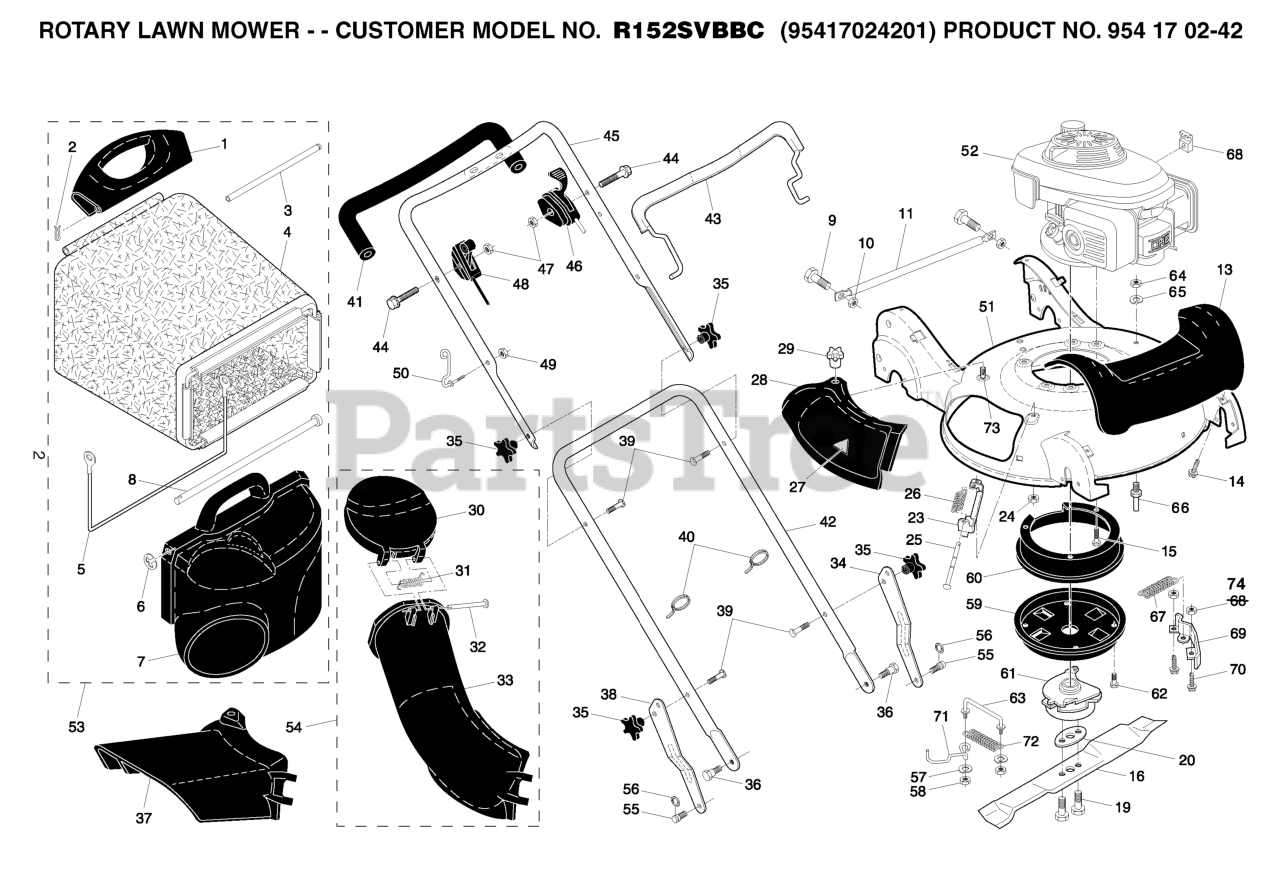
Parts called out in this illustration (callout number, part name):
1	HANDLE.GRASSBAG.REAR.H-GRAY
2	COTTER PIN (3 2)(2 2MC)
3	ROD.REAR.HANDLE.YELLOW
5	FRAME, GRASSBAG
7	DOOR, GRASSBAG
8	ROD, PIVOT
10	LOCKNUT.NYLOC.1/4-20
11	TUBE, REAR SKIRT
13	COVER, FRONT
14	SCREW
15	BOLT 3/8-16X1-1/8
16	BLADE.21".BBC
23	BRACKET.ASM.HINGE
24	LOCK NUT
25	ROD.HINGE.1/4"3.82"
26	SPRING.MULCH.DOOR
27	DECAL.INTERNATIONL.CUTFINGER
28	MULCHER DOOR
29	KNOB.MULCH.DOOR
30	CHUTE.DOOR.21.HV.H-GRAY
32	ROD.HINGE.1/4"3.82"
33	DISCHARGE CHUTE PLASTIC
34	ADJUSTMENT BRACKET, LOWER LH
35	KNOB.HANDLE.STAR.HUSQ.GRAY
36	SHOULDER BOLT
37	GUARD.CLIP.ON.21.HV.GRAY
38	BRACKET.ADJ.LOWER.HDL.RT.GREY
39	BOLT, HANDLE 5/16-18X1.75
40	TIE GUIDE
41	GRIP.HANDLE.FOAM.WIDE.(1 SIDE)
42	HANDLE.LOWER.GREY
43	BAIL
45	HANDLE.ASM.UPPER.W/GRIP
46	CONTROL.BBC.HV.GRY/ORG
47	NUT
48	THROTTLE CONTROL
50	GUIDE.ROPE.WALK.MOWER
54	CHUTE.LOWER.ASM.WALK.MOWER
55	STUD, SHOULDER
56	E-RING 7/16 RE
59	BELT COVER, LOWER
60	COVER.BELT.BBC.AW.TOP
62	TAPPING SCREW
63	LINK.TORQUE.BBC
64	NUT LOCK FLG 3/8-16 UNC
65	LOCKWASHER
66	STUC.GUIDE.BELT.RWGD
67	SPRING.BBC
68	BRACKET.THROTTLE
69	BRAKE, CLUTCH
70	BOLT
71	BELT KEEPER
72	SPRING.LINK.BBC
73	STUD.INSERT
74	NUT T
